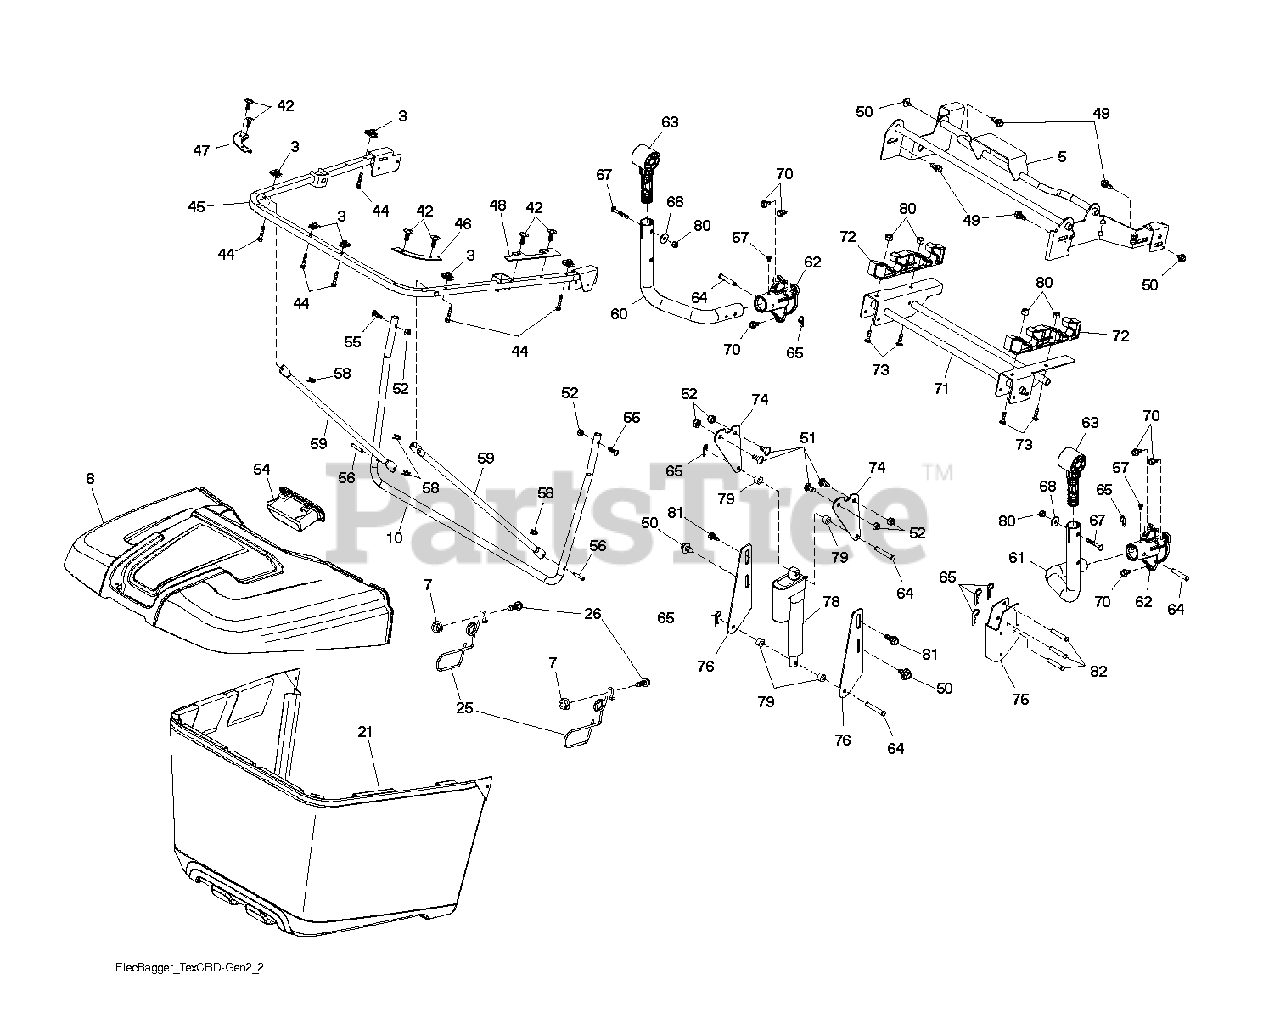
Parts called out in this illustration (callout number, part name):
3	1/4-20 U NUT
7	NUT T
26	SCREW HEX CRT
49	BOLT, SHOULDER 5/16-18
50	BOLT, 5/16-18 X 1 3/4
52	NUT.71038.31-18.HEX.NYLOCK
56	PIN.CLEVIS.183
58	RETAINER CLIP PM
65	RETAINER M
70	SCREW, 3/8-16X3/4
73	BOLT.CARRIAGE.5/16-18
80	NUT LOCK HEX FLANGE 5/16-18
81	SHOULDER BOLT 5/16-18TT
